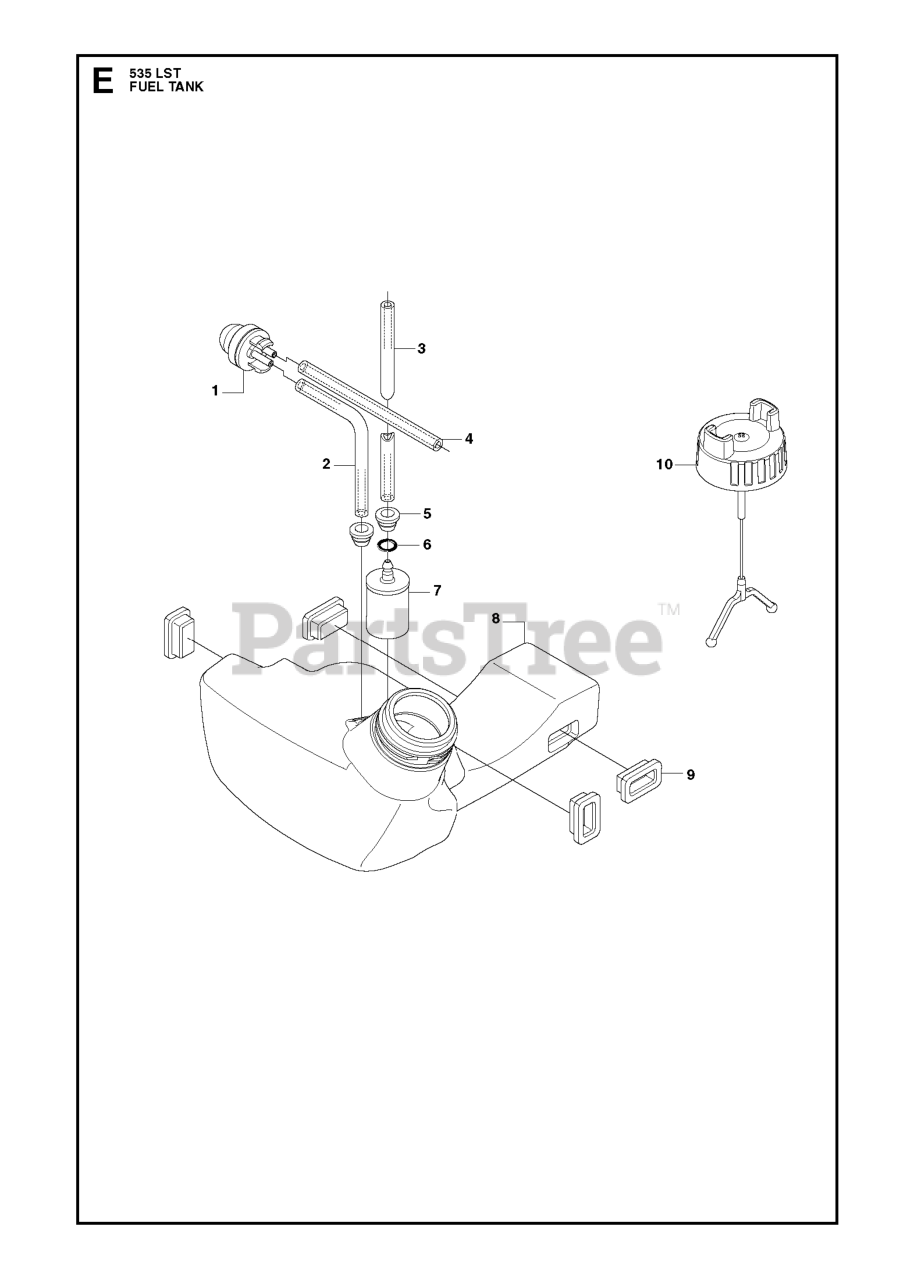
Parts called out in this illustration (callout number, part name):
1	AIR PURGE BUBBLE
3	HOSES
5	FUEL TANK BUSHING
7	RP FUEL FILTER
